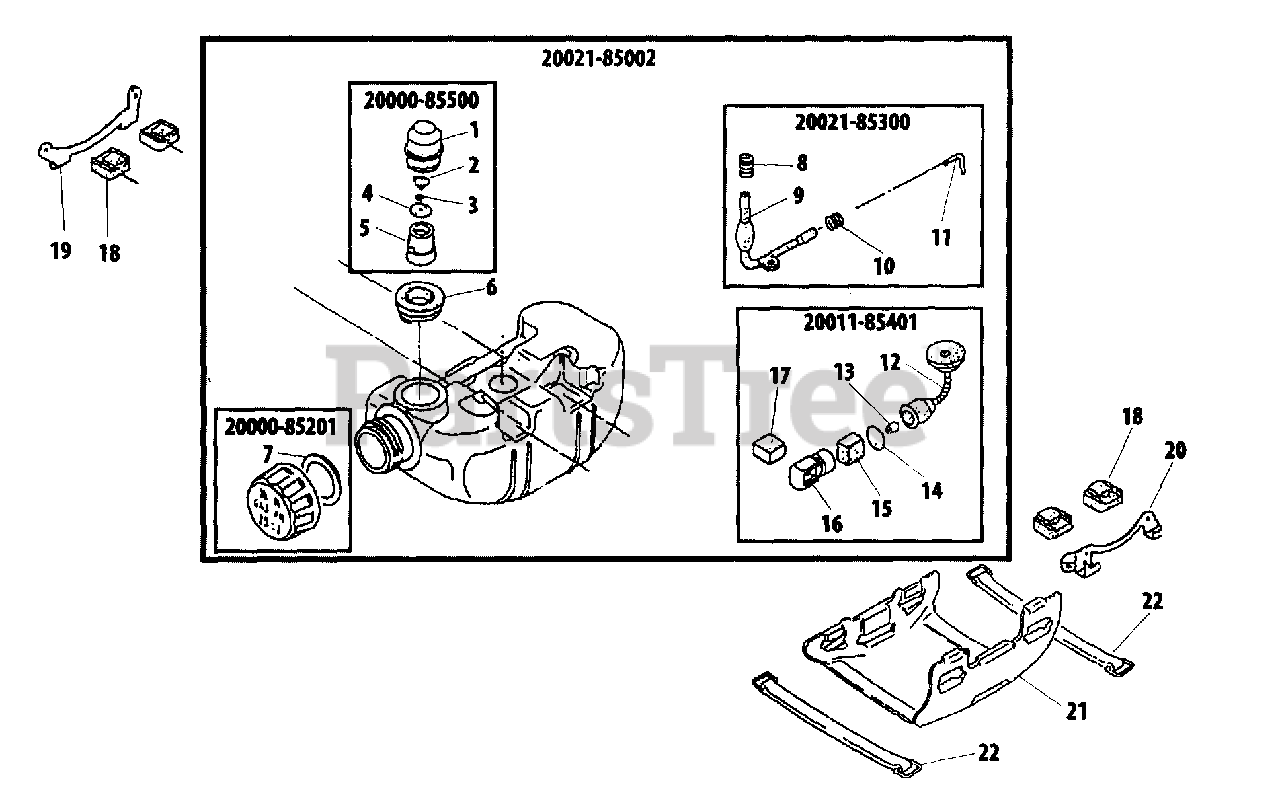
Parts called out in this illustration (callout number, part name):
1	CAP, BREATHER
2	VALVE, BREATHER
3	WASHER
4	RETAINER
5	HOLDER, VENT
6	GROMMET
7	GASKET, CAP
8	CLIP
9	PIPE - FUEL
10	RING, RETAINING
11	CONNECTOR, PIPE
12	PICK-UP TUBE
13	VENT, FUEL TANK
14	CLIP
15	FILTER, FUEL - B
16	WEIGHT, FUEL FILTER
17	FILTER, FUEL - A
18	CUSHION
19	BRACKET - INNER
20	BRACKET - OUTER
21	GUARD, FUEL TANK
22	STRAP, FUEL TANK
20000-85201	CAP ASSY
20000-85500	VENT, FUEL TANK
20011-85401	FUEL FILTER ASSY
20021-85002	FUEL TANK ASSY
20021-85300	FUEL PIPE ASSY
